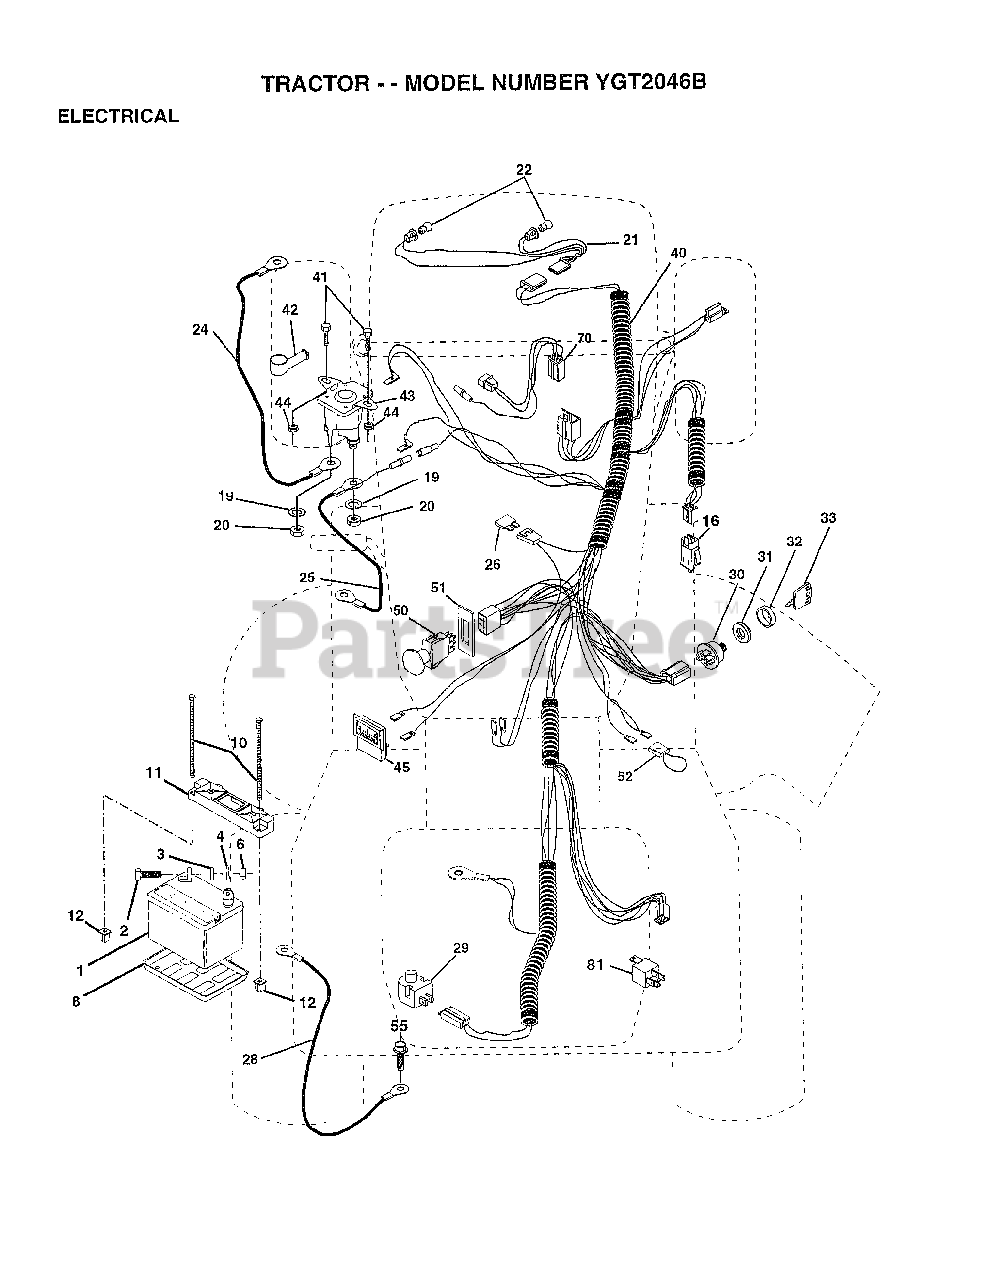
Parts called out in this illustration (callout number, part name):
3	WASHER
4	LOCKWASHER
8	"TRAY T, BATTERY"
11	HOLDDOWN BATTERY
16	SWITCH INTERLOCK
20	NUT
21	HARNESS.ASM.HDLIG
22	HEADLAMP BULB
24	"CABLE T, BATTERY"
25	CABLE.6GA.22W/16W
26	FUSE HYT
28	CABLE.GRND.6GA.21
29	SWITCH.PLUNGER
30	SWITCH IGN 4POS
31	NUT IGNITION
32	COVER KEY SWITCH
33	KEY
40	IGNITION HARNESS
41	BOLT HXHD FIN
44	NUT HXKEP 1/4X20
45	AMMETER
50	PTO SWITCH.BLK
51	RING RETAIN PTO
52	PROTECTION LOOP
70	HARNESS.ENG.B&S
81	RELAY ASSY T
